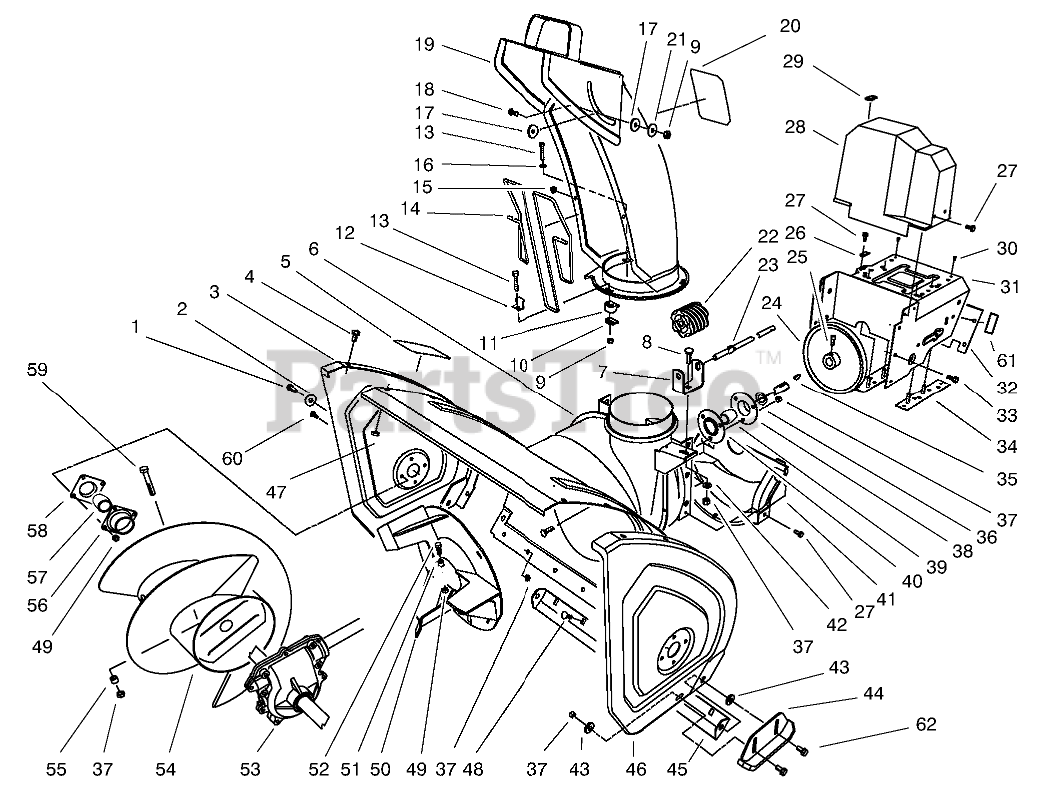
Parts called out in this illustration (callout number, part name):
1	SCREW-HH
2	WASHER
3	Plate-Side
4	SCREW-HHF
5	DECAL-WARNING, AUGER
6	Housing-28"
7	BRACKET-WORM, CHUTE
8	BOLT-CARR
9	NUT-LOCK, NI
10	PLATE-RETAINER, CHUTE
11	RETAINER-CHUTE
12	CLIP-GUARD, CHUTE
13	SCREW-HSH
14	GUARD-CHUTE
15	NUT-PUSH
16	WASHER-FLAT
17	WASHER-PLASTIC
19	Assembly
20	DECAL-DANGER (only on: 38078)
21	WASHER-FLAT
22	GEAR-WORM
23	ROD-CHUTE, LOWER
24	PULLEY-IMPELLER
25	SCREW-SET, SQH
26	RETAINER-CABLE
27	SCREW-HWH
28	COVER-BELT, UPPER
29	COVER-CABLE
30	RIVET-POP
31	Frame-Engine
32	Cover-Frame, Engine
33	SCREW-HWHTF
34	CONTROL COVER
35	KEY-WOODRUFF
36	WASHER-THRUST
37	NUT-LOCK, NI
38	FLANGE-CUP, BEARING
39	BEARING-BALL
40	FLANGE-CUP, BEARING
41	COVER-BELT, LOWER
42	WASHER-PLAIN
43	WASHER
44	Skid
45	Blade-Scraper
46	Plate-Side
47	NUT-LOCK, NI
48	SCREW-CARR
49	NUT-LOCK, NI
50	Impeller
51	SPACER
52	SCREW-HHF
53	LH AUGER GEARCASE ASM
54	Auger-R.H.
55	SPACER-HUB, AUGER
56	BEARING-FLANGE, FRONT
57	BEARING
58	BEARING-FLANGE, REAR
59	SCREW-HH
60	SCREW-HH
61	DECAL
62	Screw-Hex Washer Hd. (Incl. Ref. #38-40)
